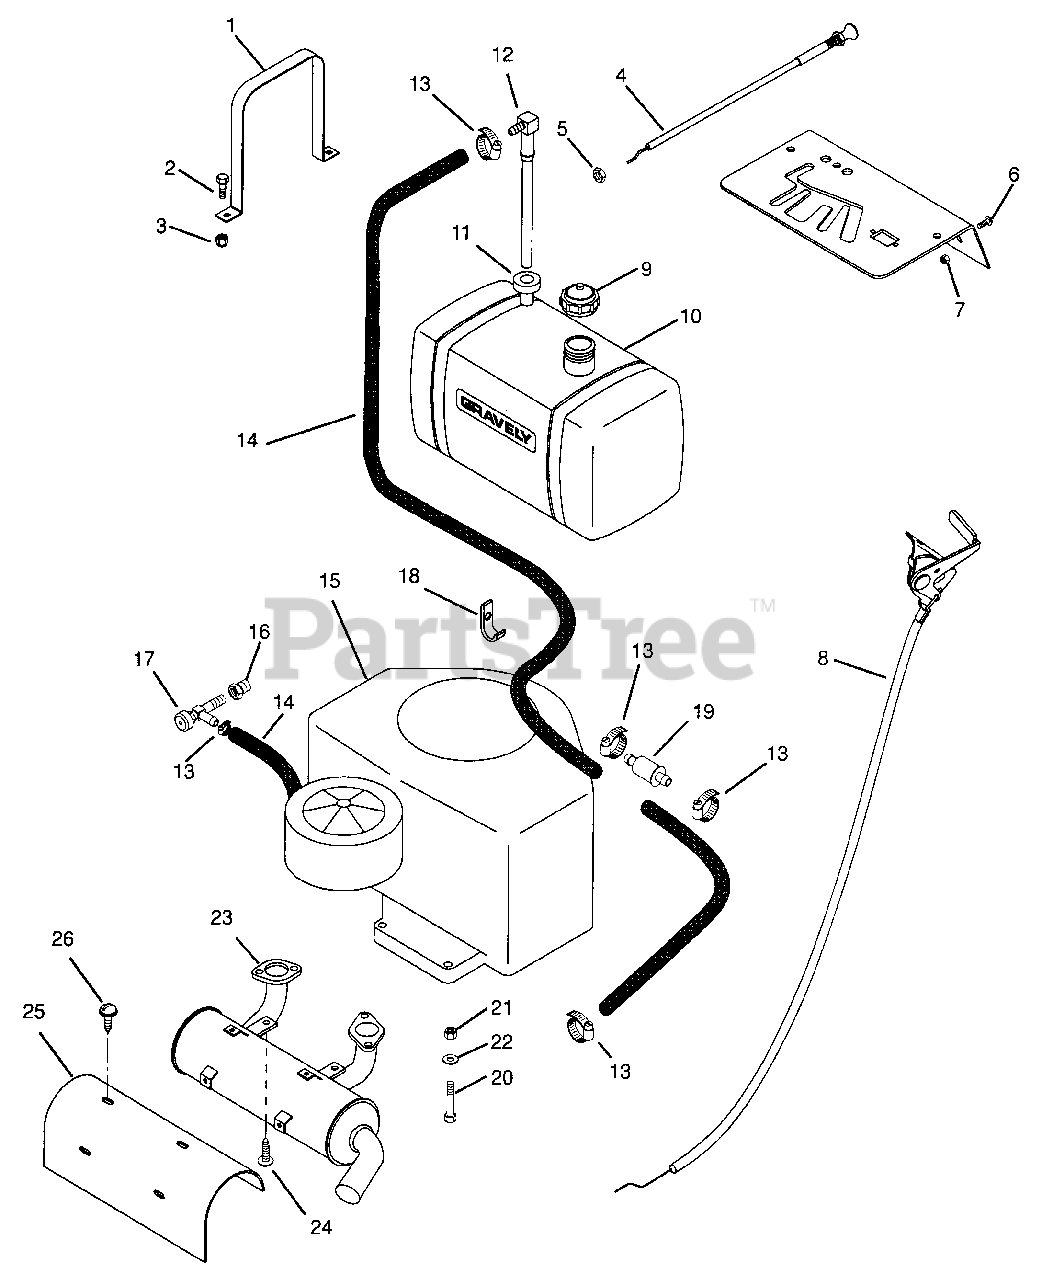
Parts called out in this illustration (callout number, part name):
1	Strap, Fuel Tank
2	Bolt-Hex .25-20 x .63
3	Nut-Locking-Nylon .250-20 Grade 2
4	Control, Choke
4	Cable, Choke
5	Nut-Jam .375-24
6	Screw-Machine 10-24 x .50
7	Nut-Locking-Nylon 10-24 with Insert
8	Assembly Throttle Control Cable
8	Throttle Control Cable Assembly
9	Cap, Fuel Tank
10	Tank, Fuel Gravely Pro
11	Bushing
12	Fitting, Tank
13	Hose Clamp
14	Gas Line - Bulk
15	Engine 16 HP Briggs Twin
15	Engine Kohler CV 18 HP PS-61541
16	Adapter, Oil Drain
17	Cock, Oil Drain
18	J-Clamp
19	Filter, Fuel
20	Bolt-Hex .31-18 x 1.75 Grade 5
21	Nut-Locking-Nylon .312-18 Grade 2
22	Washer-Flat-Steel .344 x .688 x .065
23	Muffler, Kohler CV18-CV25
23	Kit, Muffler
24	Screw-Tapping M6-1 x 25MM
25	Heat Shield
26	Screw-Tapping with Washer
